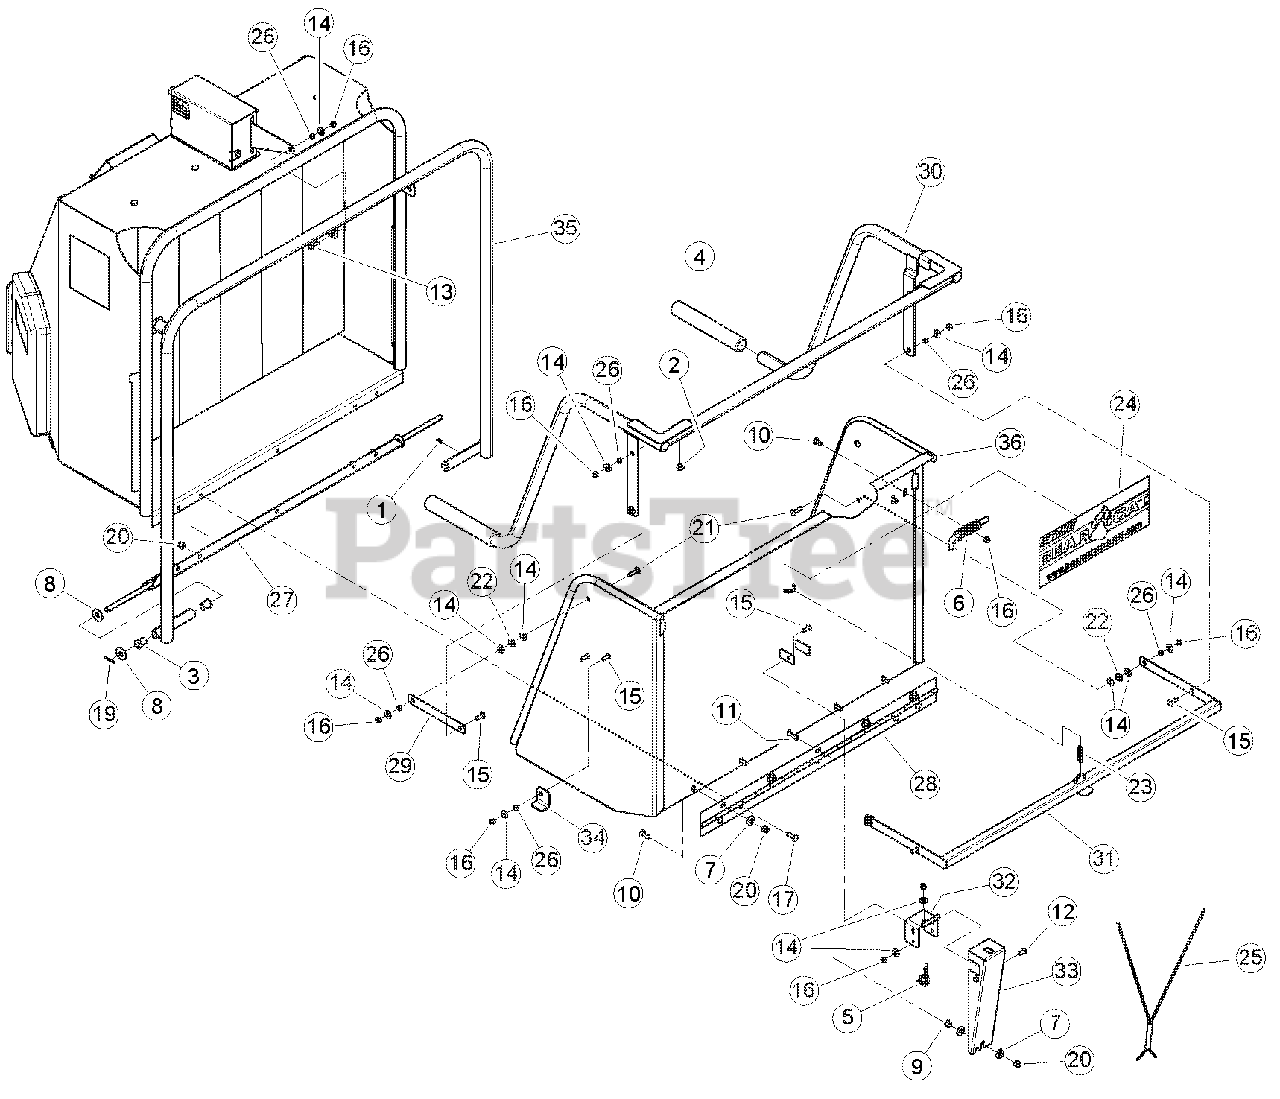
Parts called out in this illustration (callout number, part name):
1	FITTING, 1/4 SELF-TAP GREASE
2	BUMPER, RUBBER
3	BUSHING, 1/2 X 1 FLANGE LUBE
4	GRIP, 1.219 X 10.00
6	LATCH, RH HINGE
7	WASHER, 3/8 FLAT ZP
8	WASHER, 1/2 FLAT ZP
9	NUT, 3/8 SERR FLANGE NC ZP
10	BOLT, 3/8 X 1 CRG GR5 NC ZP
11	BOLT, 3/8 X 1-1/2 CRG GR5 NC ZP
12	SCREW, 11/32 X 7/8 HWH AB THREAD ZP
13	BOLT, 5/16 X 1 HEX HD GR5 NC ZP
14	WASHER, 5/16 FLAT ZP
15	BOLT, 5/16 X 1 CRG GR5 ZP
16	NUT, 5/16 NE NYLOCK ZP
17	BOLT, 3/8 X 1-1/4 HEX HD GR5 ZP
18	BOLT, 5/16 X 3/4 CRG GR5 NC ZP
19	PIN, 1/8 X 1.00 COTTER ZP
20	NUT, 3/8 NE NYLOCK ZP
21	BOLT, 5/16 X 1-1/4 CRG GR5 ZP
22	WASHER, 5/16"ID 7/8"OD NYLON FLAT
23	SPRING 1/2 X 2.00 LG,ZP
24	DECAL, BEARCAT WEB
25	HARNESS, SAFETY BAR
26	SPACER, IDLER PIVOT
27	WELDMENT, CONTROL PIVOT
28	HINGE, EXTENSION TRAY
29	LINK, PARALLEL
30	WELDMENT, KNEEBAR
31	WELDMENT, KNEEBAR PIVOT
32	BRACKET, SWITCH
33	SHIELD, KNEEBAR SWITCH
34	LOCK, SAFETY BAR
35	WELDMENT, CONTROL ARM
36	WELDMENT, EXTENSION TRAY
